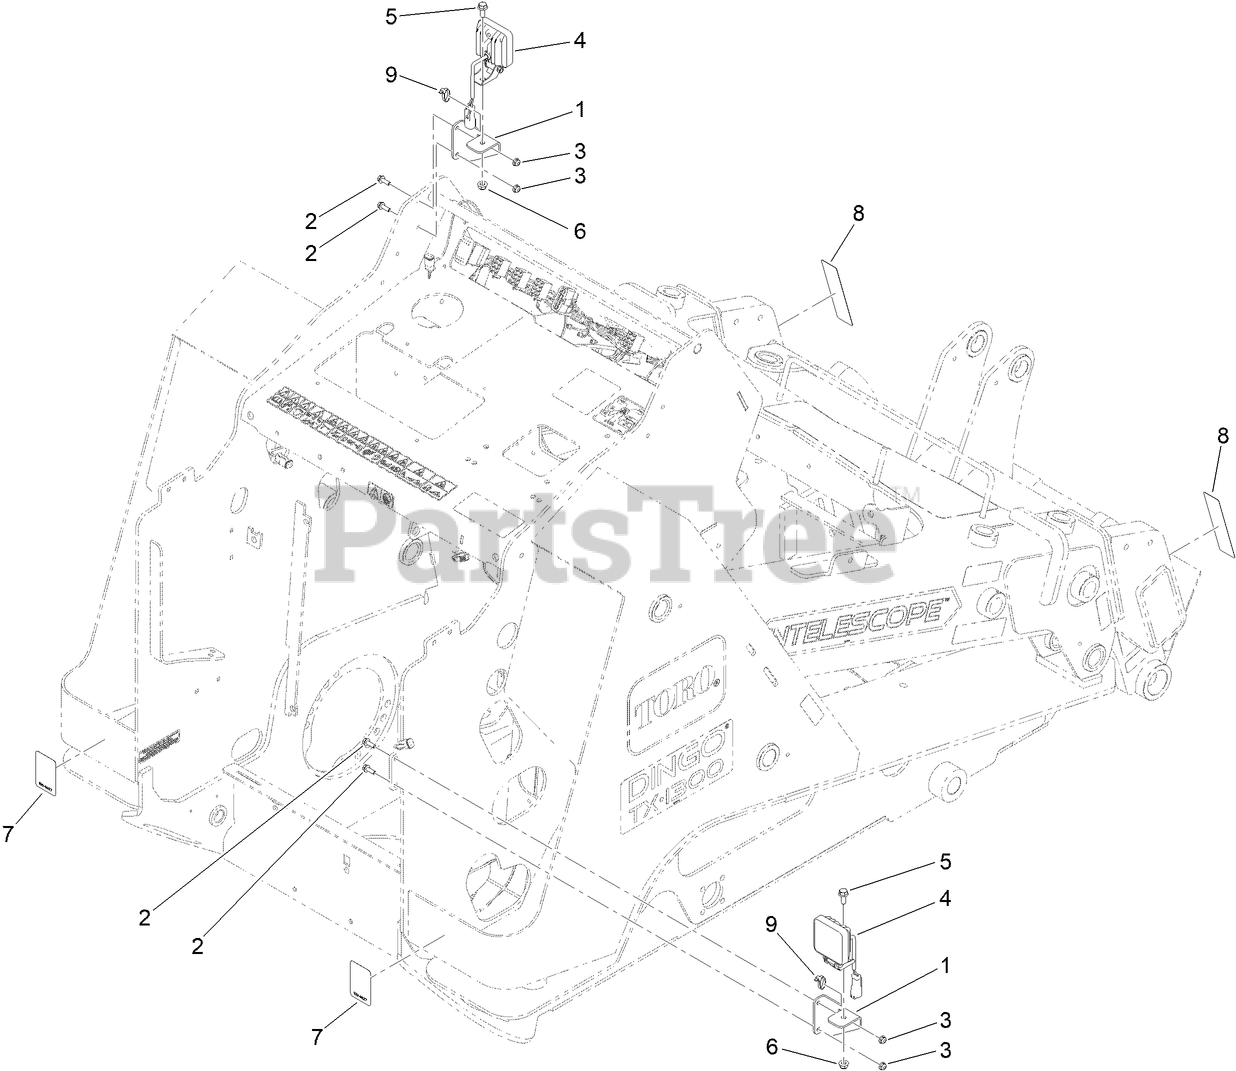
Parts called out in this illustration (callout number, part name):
1	BRACKET-LIGHT
2	SCREW-HHF
3	NUT-HF
4	LIGHT-WORK, LED
5	SCREW-HHF
6	NUT-HF, NI
7	REFLECTOR
8	TAPE-REFLECTIVE
9	TIE-CABLE
